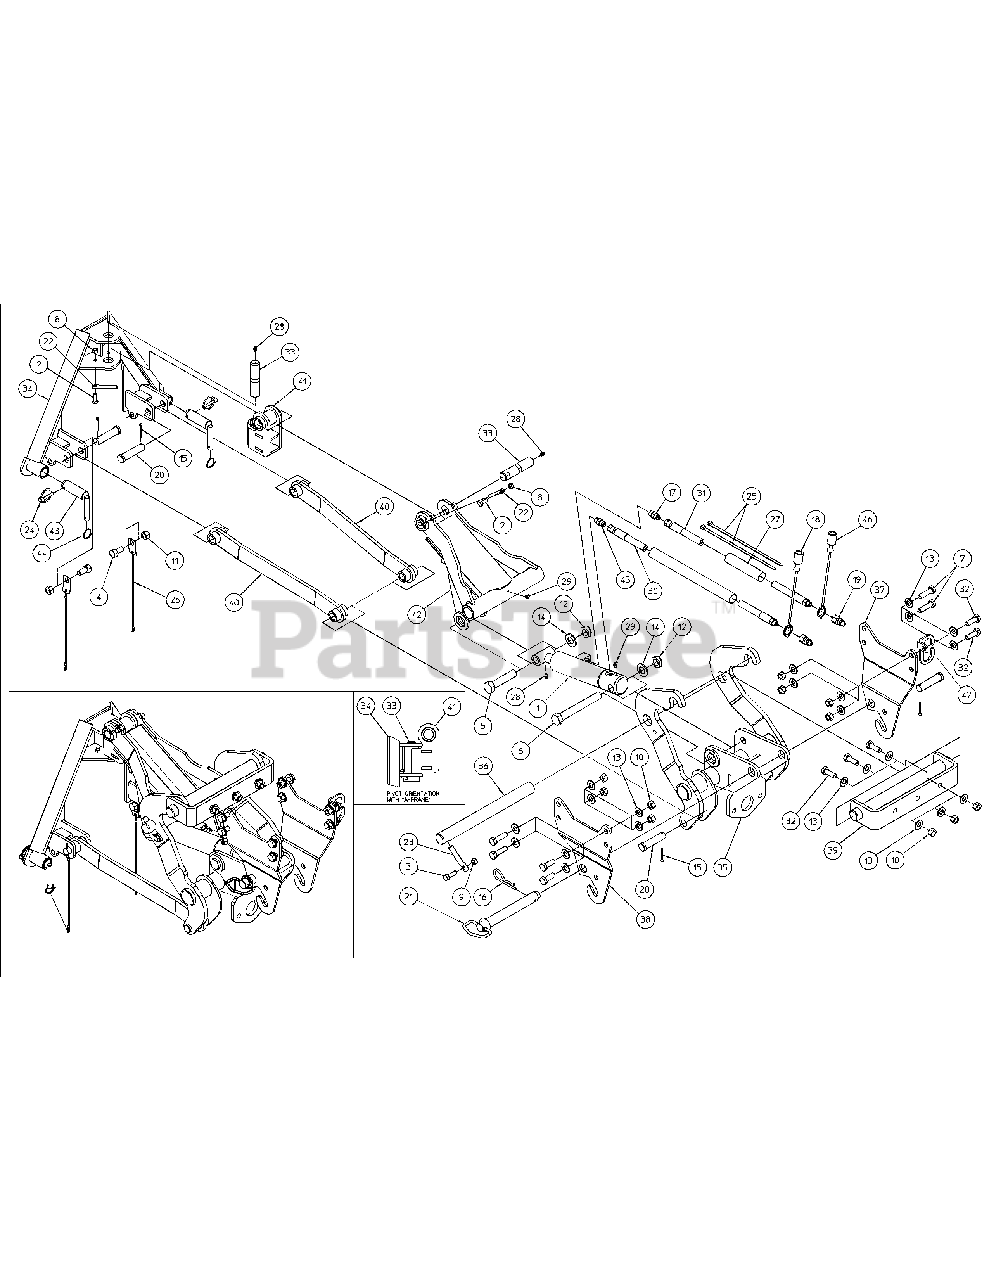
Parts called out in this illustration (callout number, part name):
1	ASSY-HYD CYLINDER (LIFT)
2	HEX HEAD CAP SCREW 5/16-24X.875 G5 ZY
3	HEX HEAD CAP SCREW 3/8-24X1.25 G5 ZY
4	HEX HEAD CAP SCREW 1/2-20X1.0 G5 SAE ZY
5	HEX HEAD CAP SCREW 3/4-16X3.75 G5
6	HEX HEAD CAP SCREW 3/4-16X6.00 G5 ZY
7	HEX HEAD CAP SCREW M12-1.75X45 G8.8 ZY FTHD
8	NUT HEX 5/16-24 ZY LOCK
9	NUT HEX 3/8-24 ZY LOCK
10	NUT HEX M12-1.75 G8.8 ZY
11	NUT HEX 1/2-20 G5 ZY LOCK
12	NUT HEX 3/4-16 ZY JAM
13	FLAT WASHER 1/2 SAE HARD ZY
14	FLAT WASHER 3/4 .812X1.469X.134 SAE ZY
15	PIN-COTTER 3/16X1.25 ZY HARDENED
16	PIN-HAIR CLIP (#6)
17	UNION STRAIGHT 06MX06M ORBXJIC
18	CAP-DUST (GREEN)
19	COUPLER-NOSE
20	PIN-CLEVIS (3/4 DIA X 3)
22	PIN-RETAINER
23	PIN-RETAINER
24	LINCH PIN,1/4 DIA X 1.25 SHAFT
25	TIE-PLASTIC (SELF LOCKING)
26	CABLE ASSEMBLY
27	SLEEVE-HOSE (1 ID X 89)
28	FITTING-STRAIGHT (GREASE) 1/4-28
29	FITTING-45 DEG (GREASE) 1/4-28
30	HOSE-HYD WITH SLEEVE (1/4 X 75)
31	HOSE-HYDRAULIC (1/4 X 85)
32	HEX HEAD CAP SCREW M12-1.75X35 GR10.9 ZY
33	PIN-PIVOT (BUCKET CYL-KNEE)
34	WELDMENT- MOUNT (A-FRAME)
35	WELDMENT- HITCH FRAME (SX)
36	SHAFT-PIVOT
37	PLATE-RH MOUNT BRACKET
38	PLATE-LH MOUNT BRACKET
39	WELDMENT-HANGER (SX)
40	WELDMENT-LINK
41	WELDMENT-PIVOT
42	WELDMENT-PIVOT LINK
43	WELDMENT-PIN
44	RING-LOCKING
45	UNION STR 06MX06M ORBXJIC
46	CAP-DUST (BLUE)
47	PLATE-HOSE GUIDE
